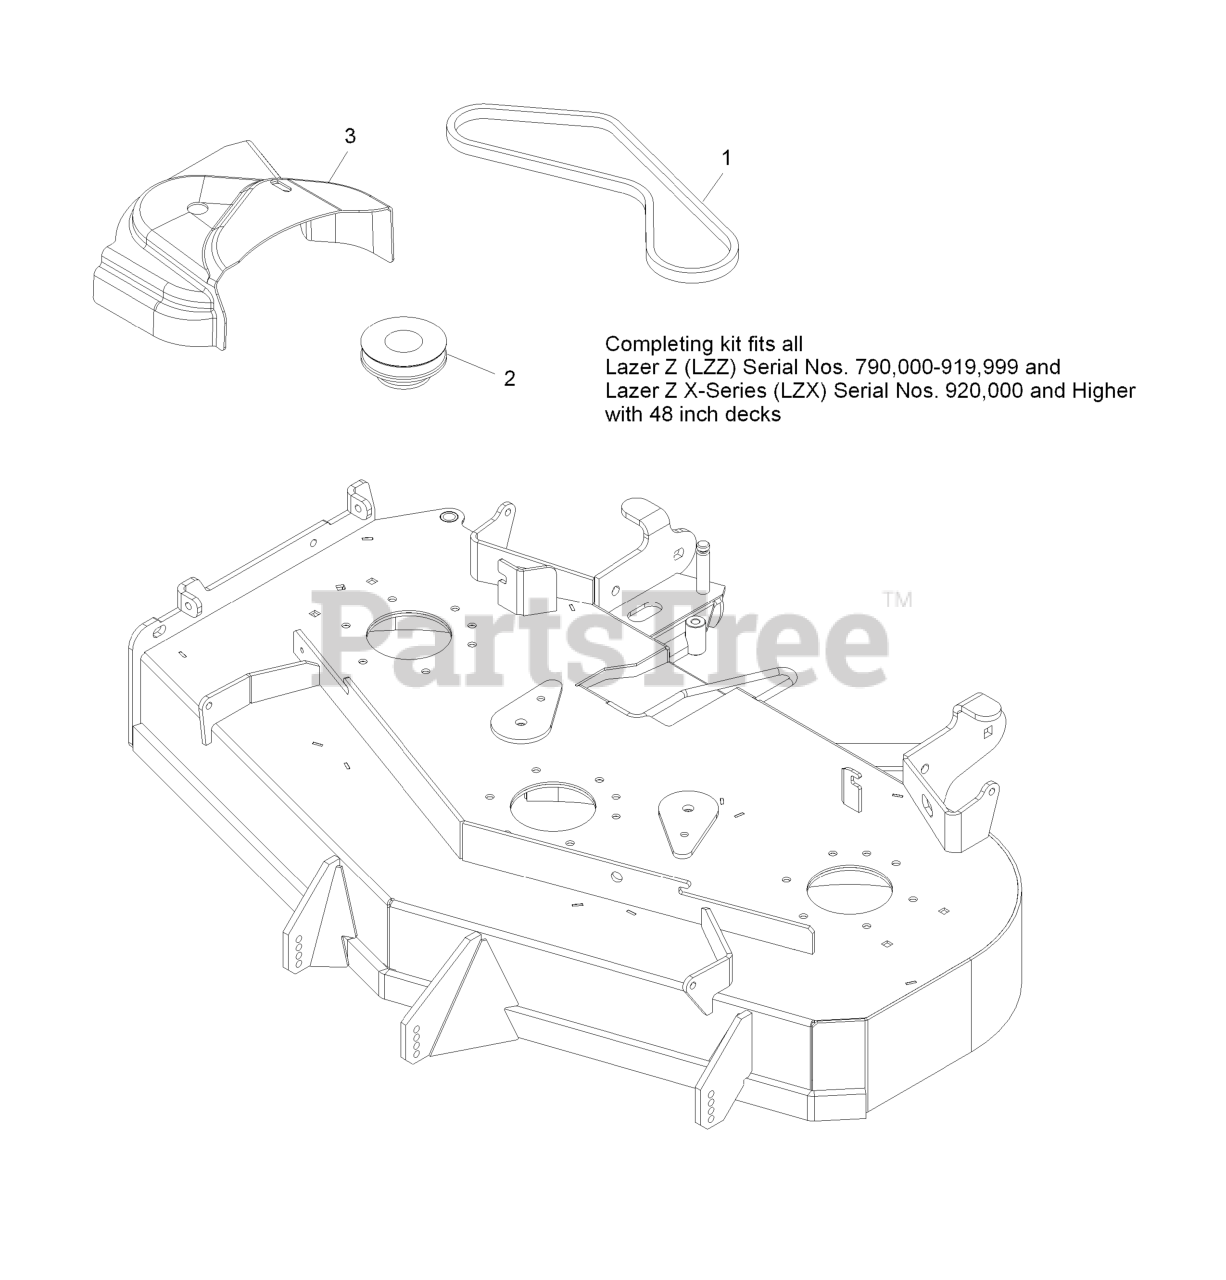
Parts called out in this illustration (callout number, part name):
1	BELT-BLOWER
2	SHEAVE,DRIVE LZUV 486
3	COVER,BELT UV 48
